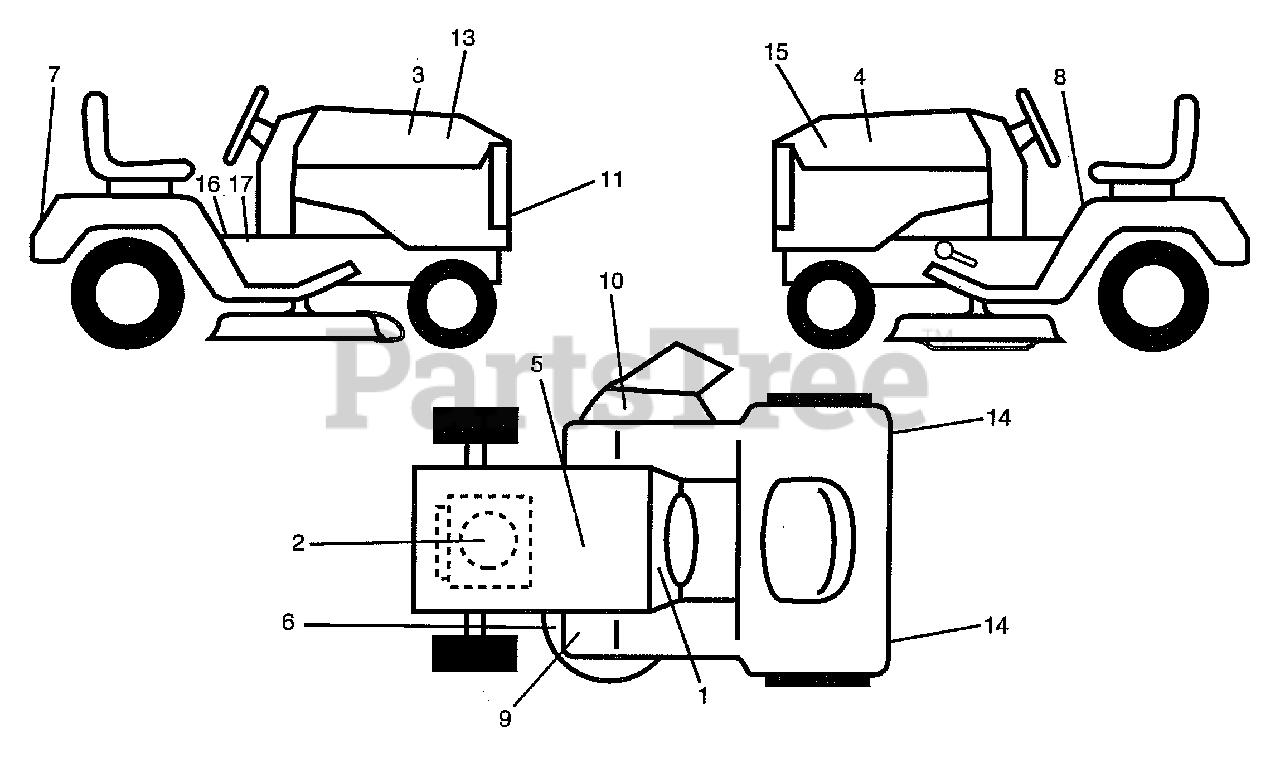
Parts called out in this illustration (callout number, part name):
1	Decal Instruction Dash Eng/fr
2	Decal HP Engine
3	Decal Hood RH Husq YT180 Insert
4	Decal Hood LH Husq YT180 Insert
5	Decal Caution Battery Fr/ger
6	Decal V-Belt Sch
7	Decal Fender Husqvarna
8	Decal Caution Fender Eng/fr
9	Decal Clutch/brake Eng/fr
10	Decal Warning MULT-LANGUAGE
11	Decal Grille Husqvarna
13	Decal Hood RH Husqvarna
14	Reflector Tail Light Red/amber
15	Decal Hood RH Husqvarna
16	Decal Sdl Cold Start Hyd E/F
17	Decal Brake Parking Saddle
